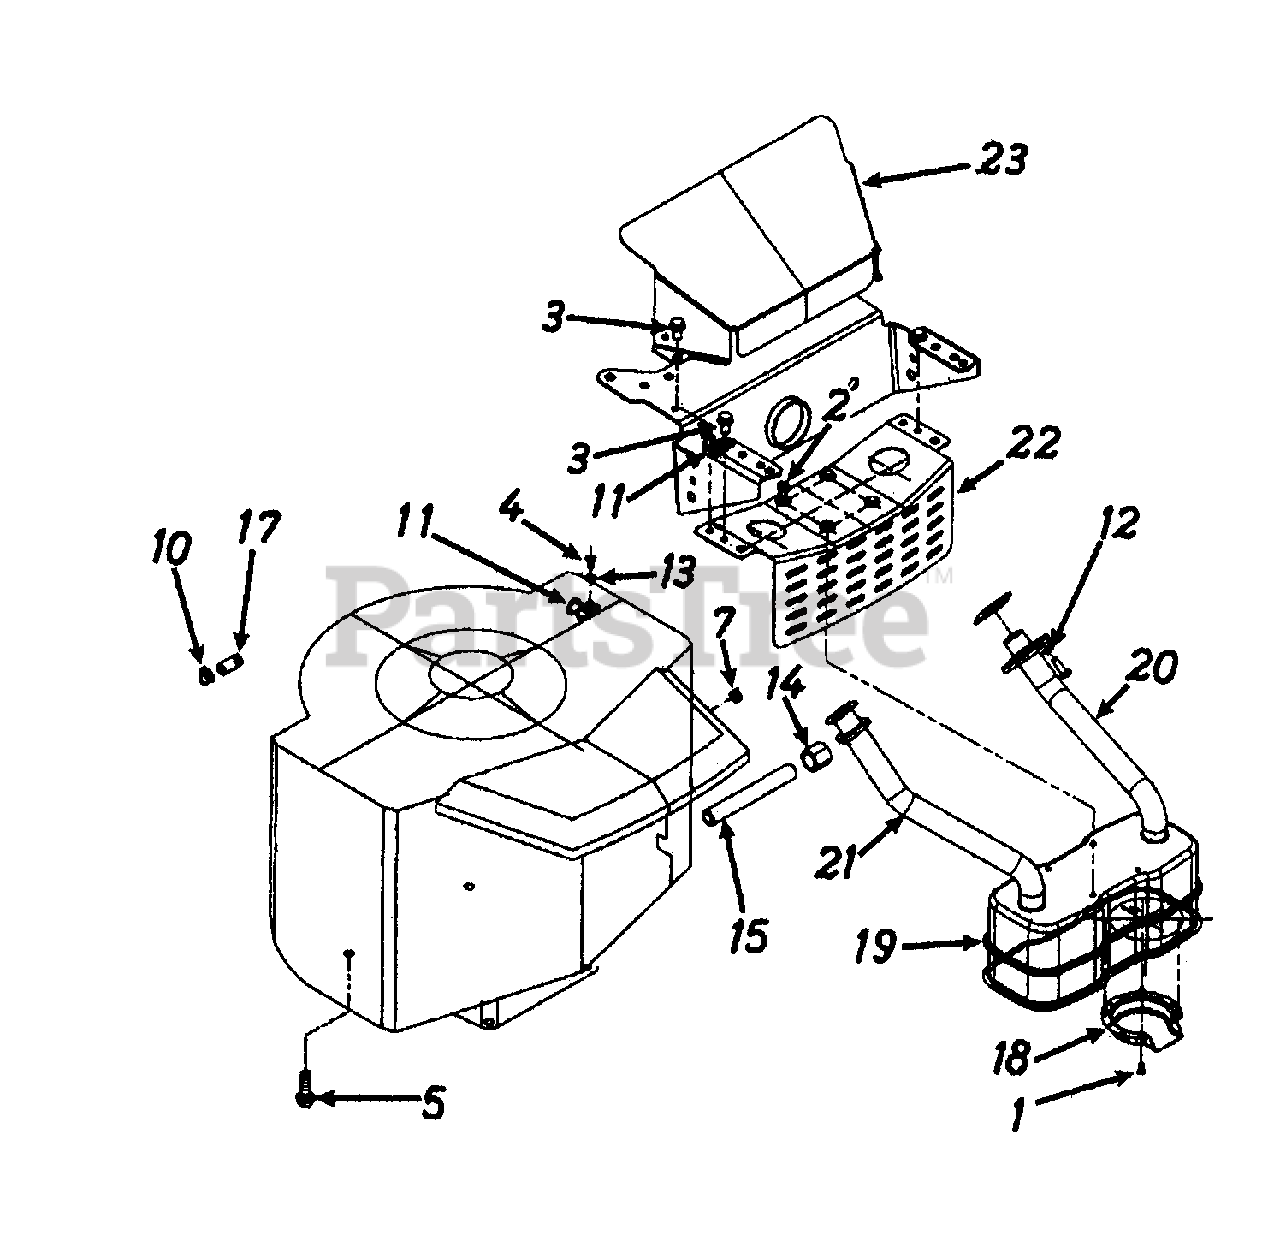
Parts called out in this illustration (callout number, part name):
1	Hex Tap Scr. #8-32 x .38" Lg.
2	Hex Wash. TT-Tap Scr. 1/4-20 x5" Lg.
3	Hex Wash. TT-Tap Scr. 5/16-18 x .62" Lg.
4	Truss Mach. Scr. #10 x .5" Lg.
5	Hex Hd. Tap Scr. 3/8-16 x 1.25"Lg.
7	Hex Sems Nut 1/4-20 Thd.
10	Hose Clamp
11	Clamp
12	L-Wash. 1/4" I.D.
13	Fl-Wash. .188" I.D. x .438" O.D.
14	Oil Drain Cap
15	Pipe Nipple 3/8 x 18 NPT.
17	Fuel Line 26" Lg.
18	Deflector: Muffler
19	Muffler
20	Exhaust Pipe-L.H.
21	Exhaust Pipe-R.H.
